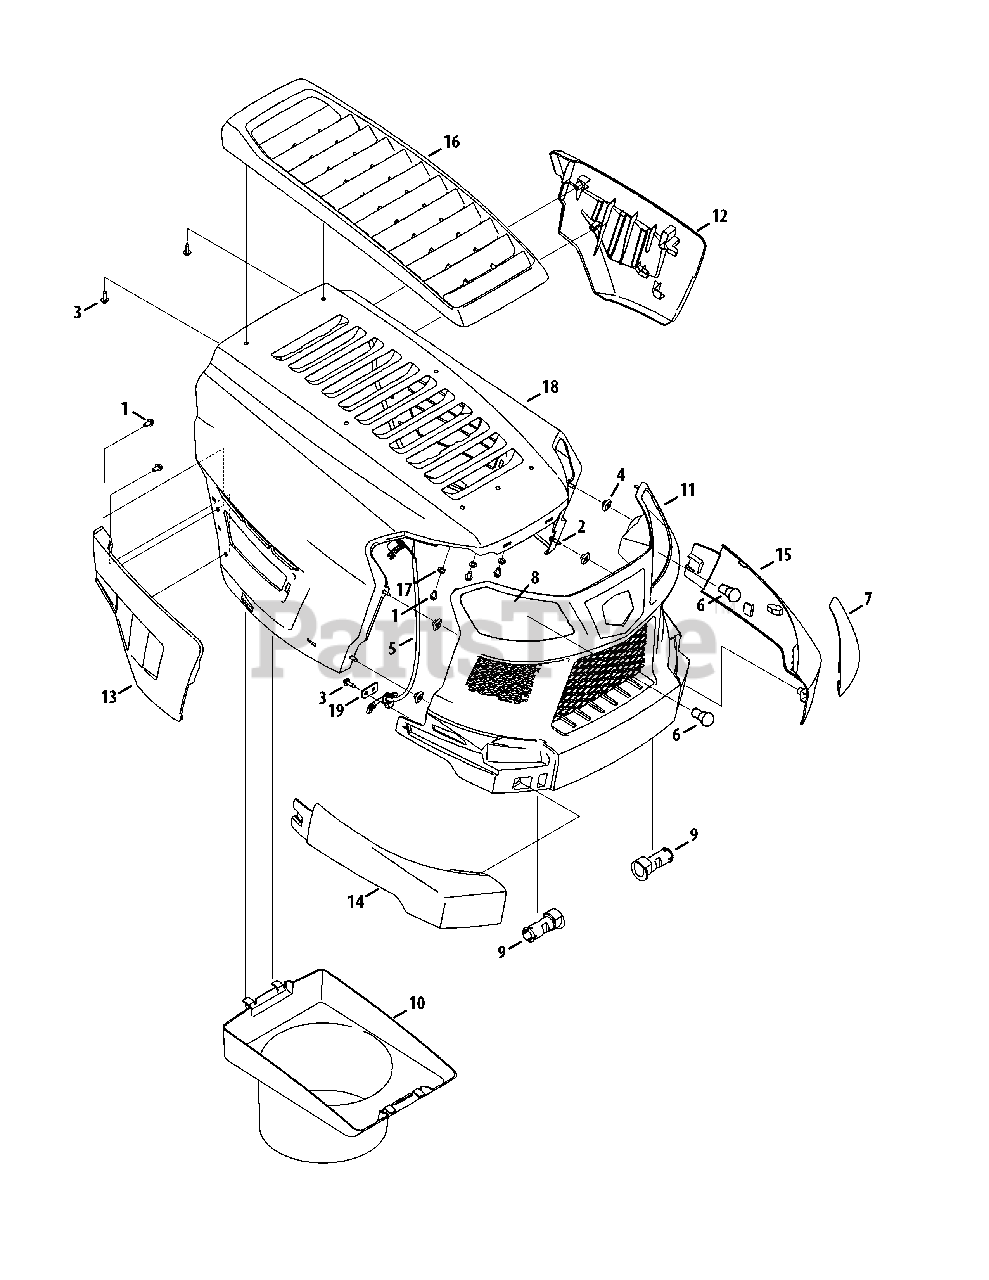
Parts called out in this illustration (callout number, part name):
1	Screw, 1/4-15 x 0.50
2	Hex Cap Screw, 1/4-20 x .625
3	Screw, 1/4 x .750
4	Nut, 1/4-20, .433 x .170
5	Headlight Harness
6	Miniature lamp 12V socket
7	Grill Lens - LH
8	Grill Lens - RH
9	Hood Pin
10	Plenum
12	Side Cover, LH
13	Side Cover, RH
14	Grill Panel, RH
15	Grill Panel, LH
16	Hood Scoop
17	Flat Washer, .281 x .500 x .063
18	Hood
19	Harness Bracket
